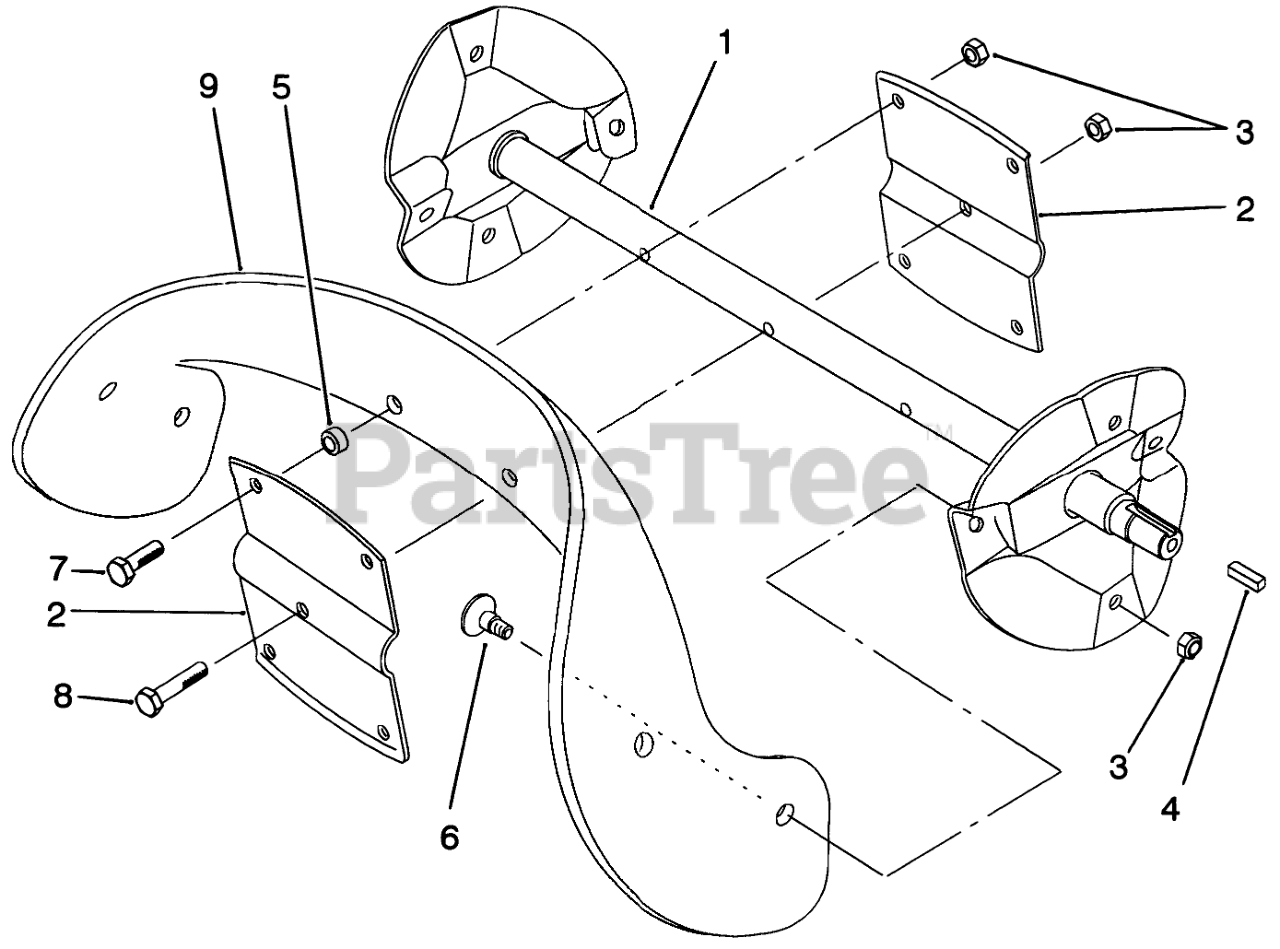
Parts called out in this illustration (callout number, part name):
1	Wa-Rotor
2	Rotor
3	NUT-LOCK, NI
4	KEY-SQUARE
5	SPACER-BLADE, ROTOR
6	SCREW
7	SCREW-HH
8	SCREW-HH
9	Blade-Rotor
